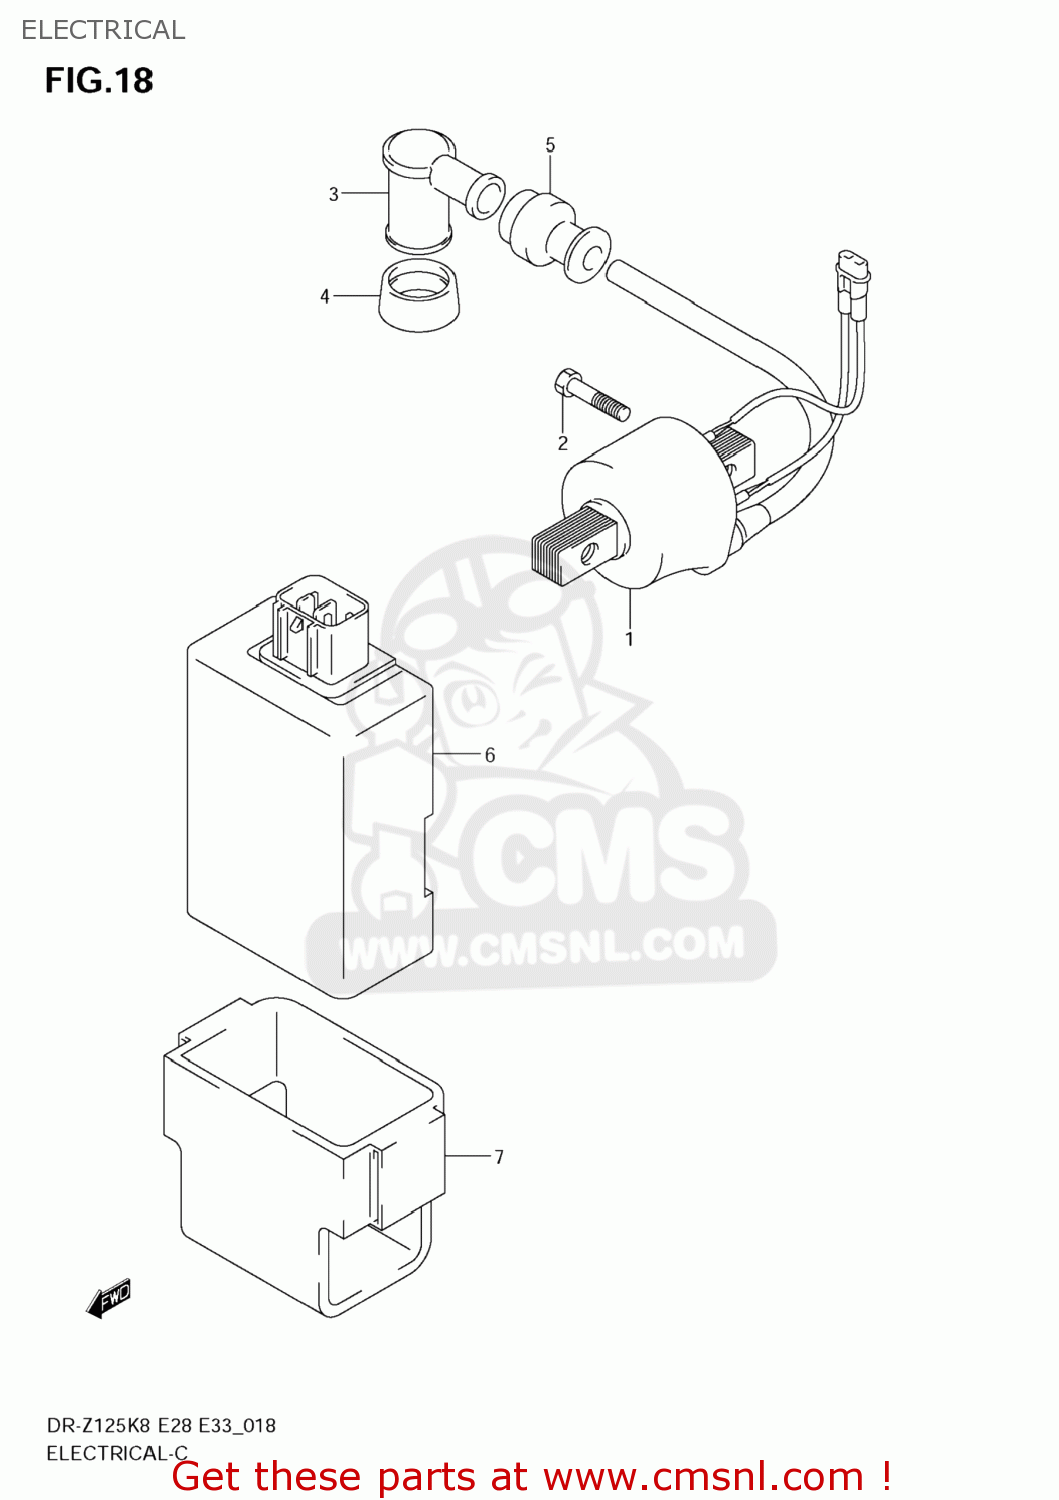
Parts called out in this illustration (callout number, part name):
1	COIL ASSY,IGNITION
2	BOLT
3	CAP ASSY,SPARK PLUG
4	SEAL,SPARK PLUG
5	SEAL,HIGH TENSION CORD
6	CDI UNIT
7	CUSHION,CDI UNIT
